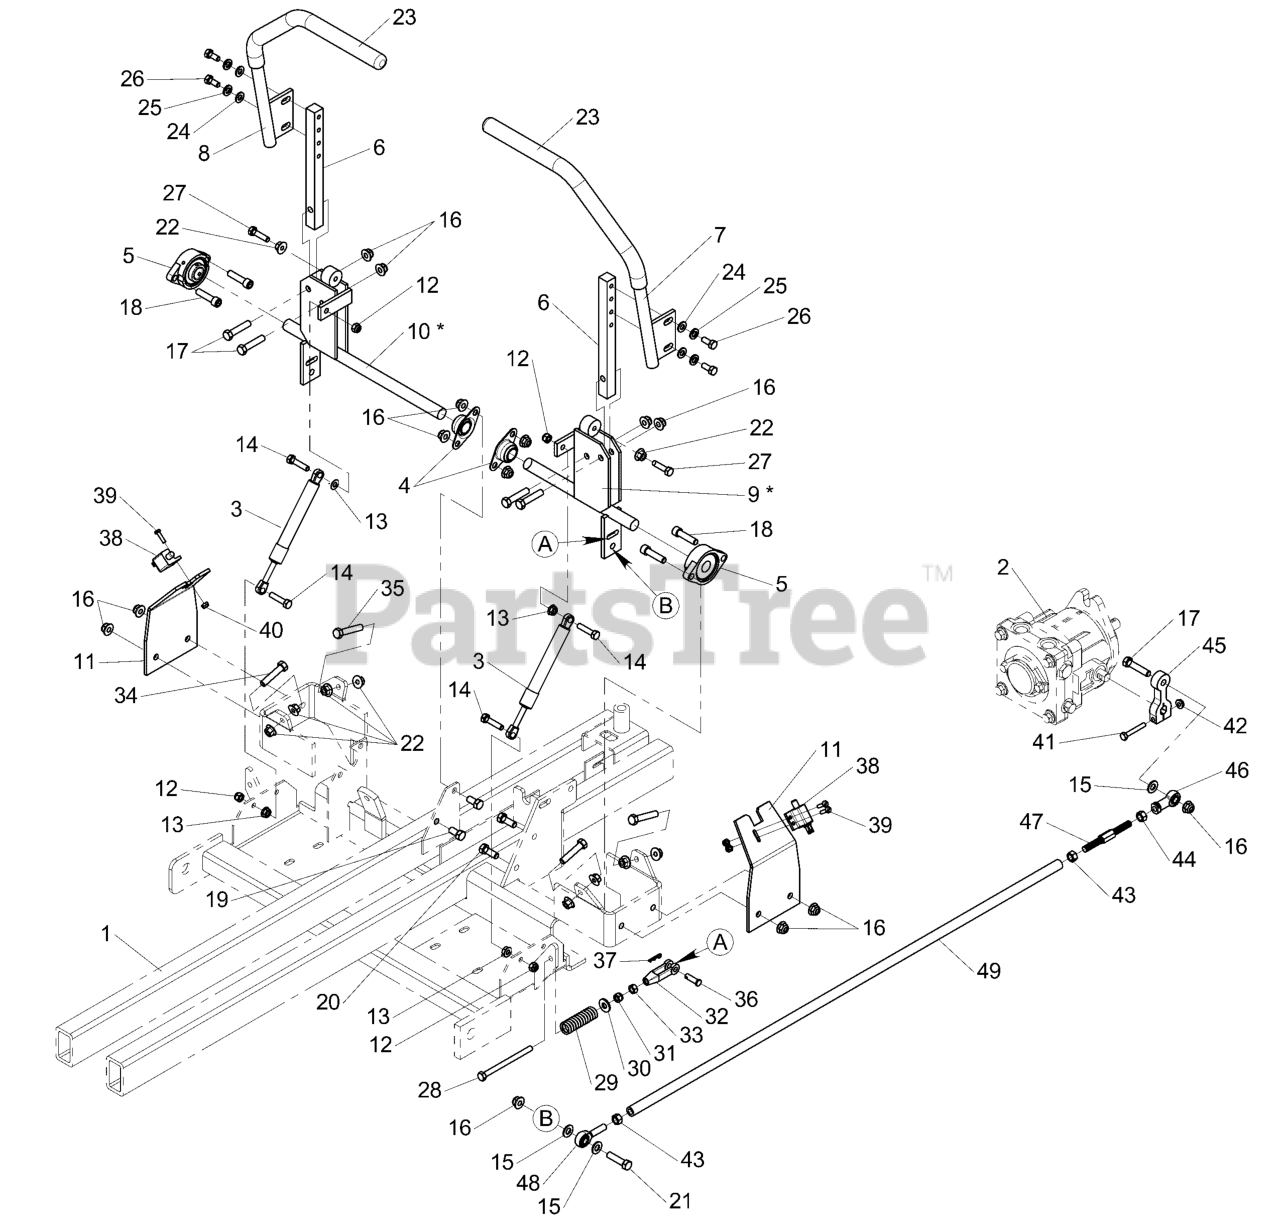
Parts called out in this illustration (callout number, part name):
1	MAIN FRAME
2	HYDRAULIC PUMP
3	DAMPENER
4	BEARING, BRONZE FLANGE, 3/4
5	BEARING, FLANGE
6	MOUNT, CONTROL ARM - BLK
7	WELD, HANDLE MOTION CONTROL-LH
8	WELD, HANDLE MOTION CONTROL, RH - RED
9	MOTION CONTROL SHAFT - LH
9	WELD, SHAFT MOTION CONTROL-LH
10	MOTION CONTROL SHAFT - RH
10	WELD, SHAFT MOTION CONTROL-RH
11	PLATE, NEUTRAL LOCK - RED
12	NUT, M8-1.25 NYLON LOCK, CZ
13	NUT, M8-1.25 SERR. FLANGE, CZ
14	BOLT, M8-1.25 X 35MM, GD8.8
15	WASHER, 3/8 SAE
16	NUT, 3/8-16 HEX NYLOCK FLANGE
17	BOLT, 3/8-16 X 1-3/4" GD5 CZ
18	BOLT, 3/8-16 X 1-1/2, SOC HD, GD5, CZ
19	BOLT, 3/8-16 X 3/4" GD5 CZ
20	BOLT, 3/8-16 X 1" GD5 CZ
21	BOLT, 3/8-16 X 1-1/2" GD5 CZ
22	NUT, 5/16-18 HEX SERRATED FLANGE (LARGE)
23	GRIP, FOAM, 3/4" ID, 16"" LONG
24	WASHER, 5/16" SAE
25	WASHER, 5/16 LOCK CZ
26	BOLT, 5/16-18 X 1" GD5 YZ
27	BOLT, 5/16-18 X 1-1/4" GD5 YZ
28	BOLT, 5/16-24 X 4.25" GD5 YZ
29	SPRING, REVERSE RETURN
30	WASHER, 5/16" USS
31	NUT, 5/16-24 HEX NYLON LOCK
32	CLEVIS, 5/16-24, PLASTIC
33	NUT, 5/16-24 HEX
34	BOLT, 5/16-18 X 1-3/4" GD5 TFL
35	BOLT, 5/16-18 X 2" GD5 TFL
36	CLEVIS PIN, 5/16 x 1
37	PIN, HAIR, .0585" X 1-1/8"
38	SWITCH, PLUNGER, N.O.
39	SCREW, #10-24 X 1/2" ROUND PHILLIPS
40	NUT, #10-24 HEX
41	BOLT, 1/4-20 X 1-3/4" GD5 YZ
42	NUT, 1/4-20 HEX NYLOCK FLANGE
43	NUT, 3/8-24 HEX
44	NUT, 3/8-24 HEX LH
45	ARM, PUMP CONTROL (21 SERIES)
46	ROD END, 3/8-24 LH FEMALE
47	LINK, ADJUSTABLE, SHORT
48	BALL JOINT, 3/8-24 MALE
49	ROD, CONTROL
